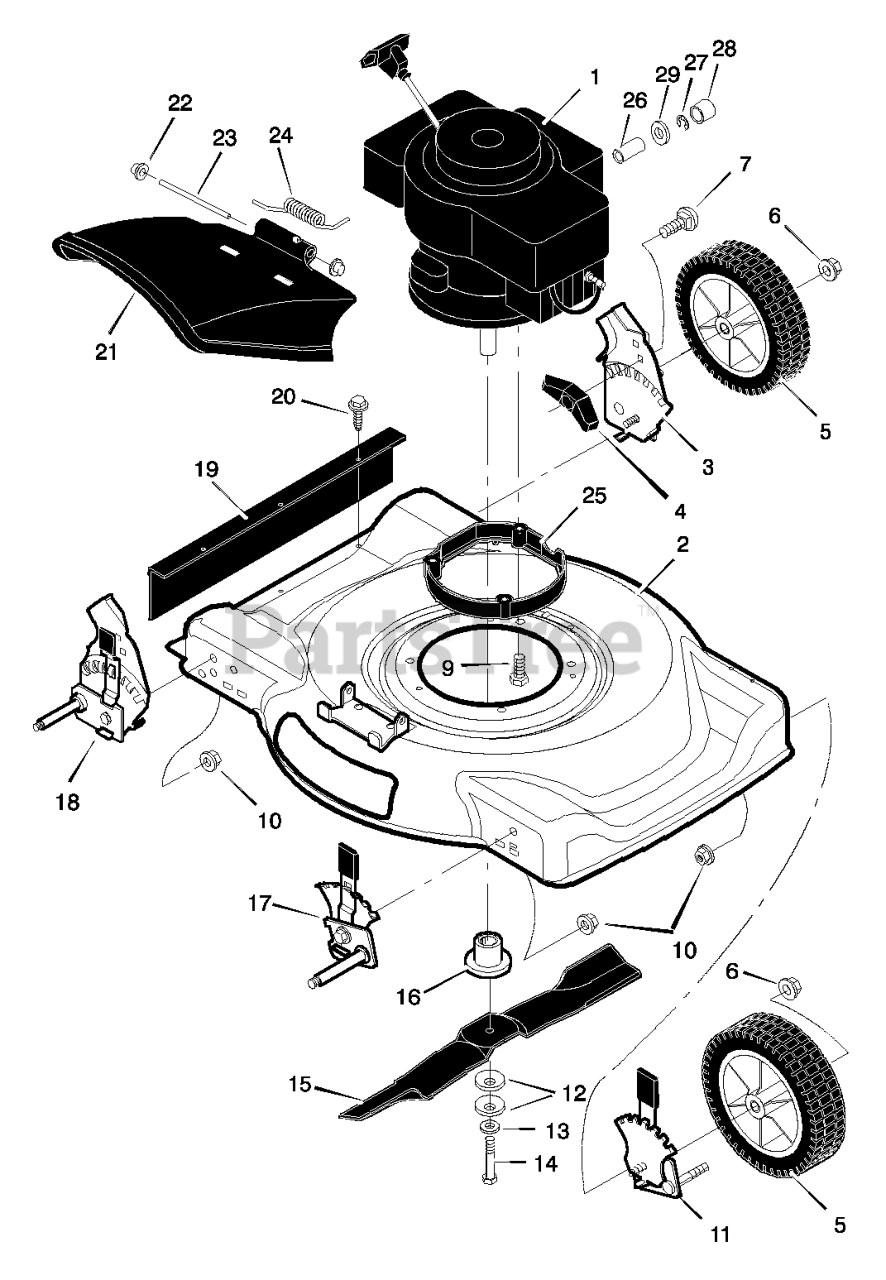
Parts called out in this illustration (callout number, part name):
1	Engine *
2	Housing
3	Height Adjuster, Left Rear
5	Wheel and Tire *
6	Locknut, Flange
7	Bolt, Carriage
9	Bolt, Engine
10	Nut
11	Height Adjuster, Left Front
12	Washer, Belleville
14	Bolt, Hex
16	Adapter, Blade
17	Height Adjuster, Right Front
18	Height Adjuster, Right Rear
19	Guard, Rear
21	Deflector, Chute
22	Push-On Cap
23	Pin, Pivot
25	Base, Engine
27	E-Ring
29	Washer
